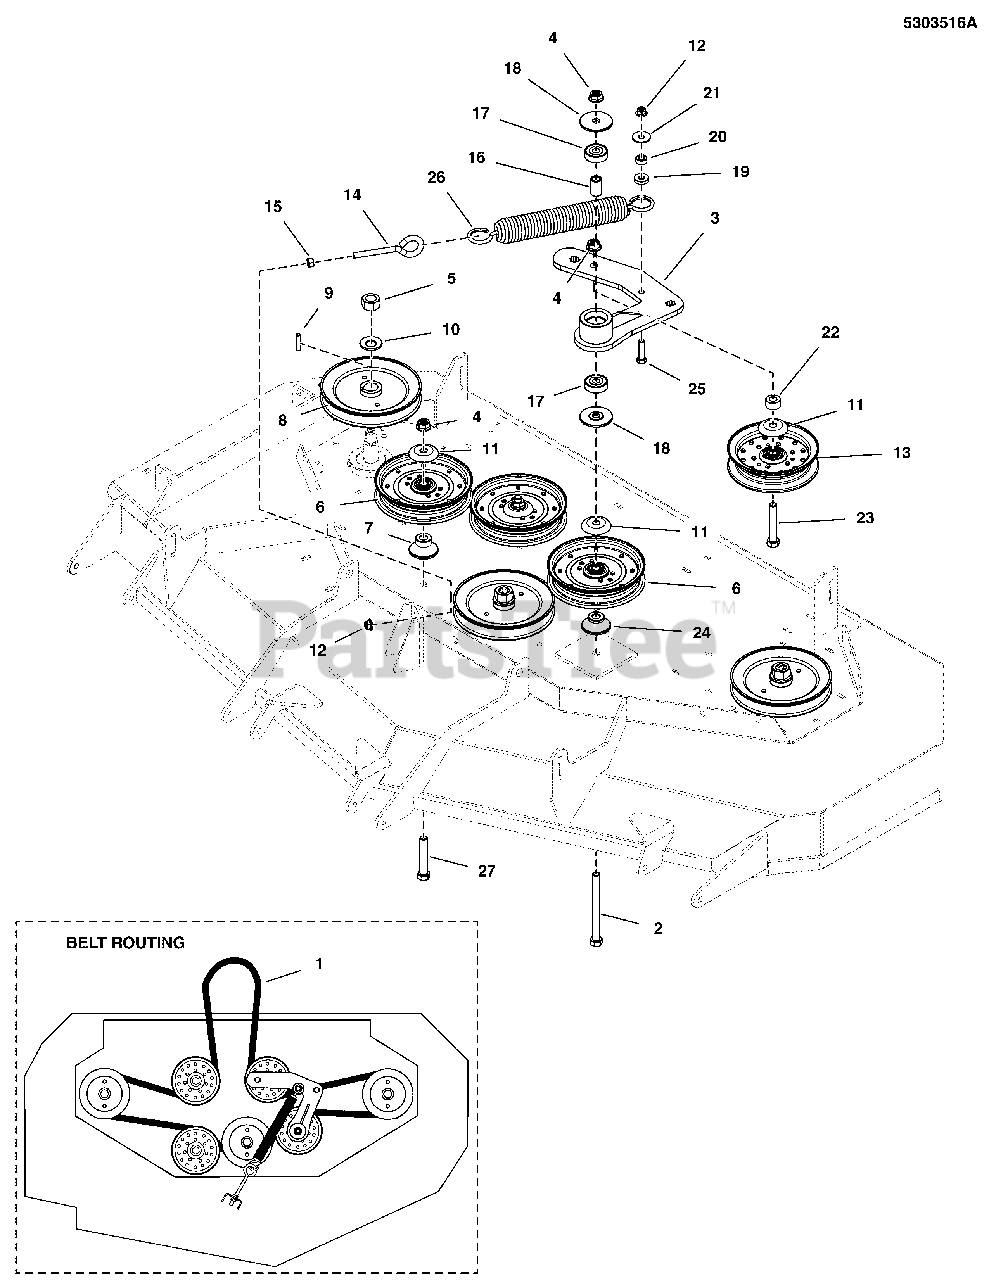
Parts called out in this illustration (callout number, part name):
1	BELT, 5V, 178.25"EL, ARAMID, WRAP RC
2	BOLT, 1/2-13 X 5-1/2 GD5 CZ
3	WELD, IDLER ARM - BLK
4	NUT, 1/2-13 HEX NYLOCK FLANGE
5	NUT, 3/4-16 HEX
6	PULLEY, FLAT IDLER, 6-3/4"
7	IDLER MOUNT
8	PULLEY, 6.93 EOD X 25MM, SPLIT
9	KEY, 1/4 SQ X 1-1/4
10	WASHER, 3/4 BELLEVILLE
11	SHIELD, PULLEY BEARING, CZ
12	NUT, 3/8-16 HEX NYLOCK FLANGE
14	EYE BOLT, 3/8-16 X 5, 2.88THRD, 1EYE, CZ
15	NUT, 3/8-16 HEX
16	SPACER, .51 X .75 X 1.22, PM, CZ
17	BEARING, 6203-1/2", SEALED
18	SPACER, IDLER ARM, 1/2 X 2.25
19	SPACER, .39 X 1.00 X .25
20	SPACER, .39 X .75 X .38
21	WASHER-3/8 FENDER
22	SPACER, .52 X 1.00 X .56, CZ
23	BOLT, 1/2-13 X 2-1/2 GD5 CZ
24	IDLER MOUNT, .88 HIGH
25	BOLT, 3/8-16 X 1-1/2 GD5 CZ
26	SPRING, EXT, 1.5ODX12.25X.234WIRE BLK
27	BOLT, 1/2-13 X 3 GD5 CZ
